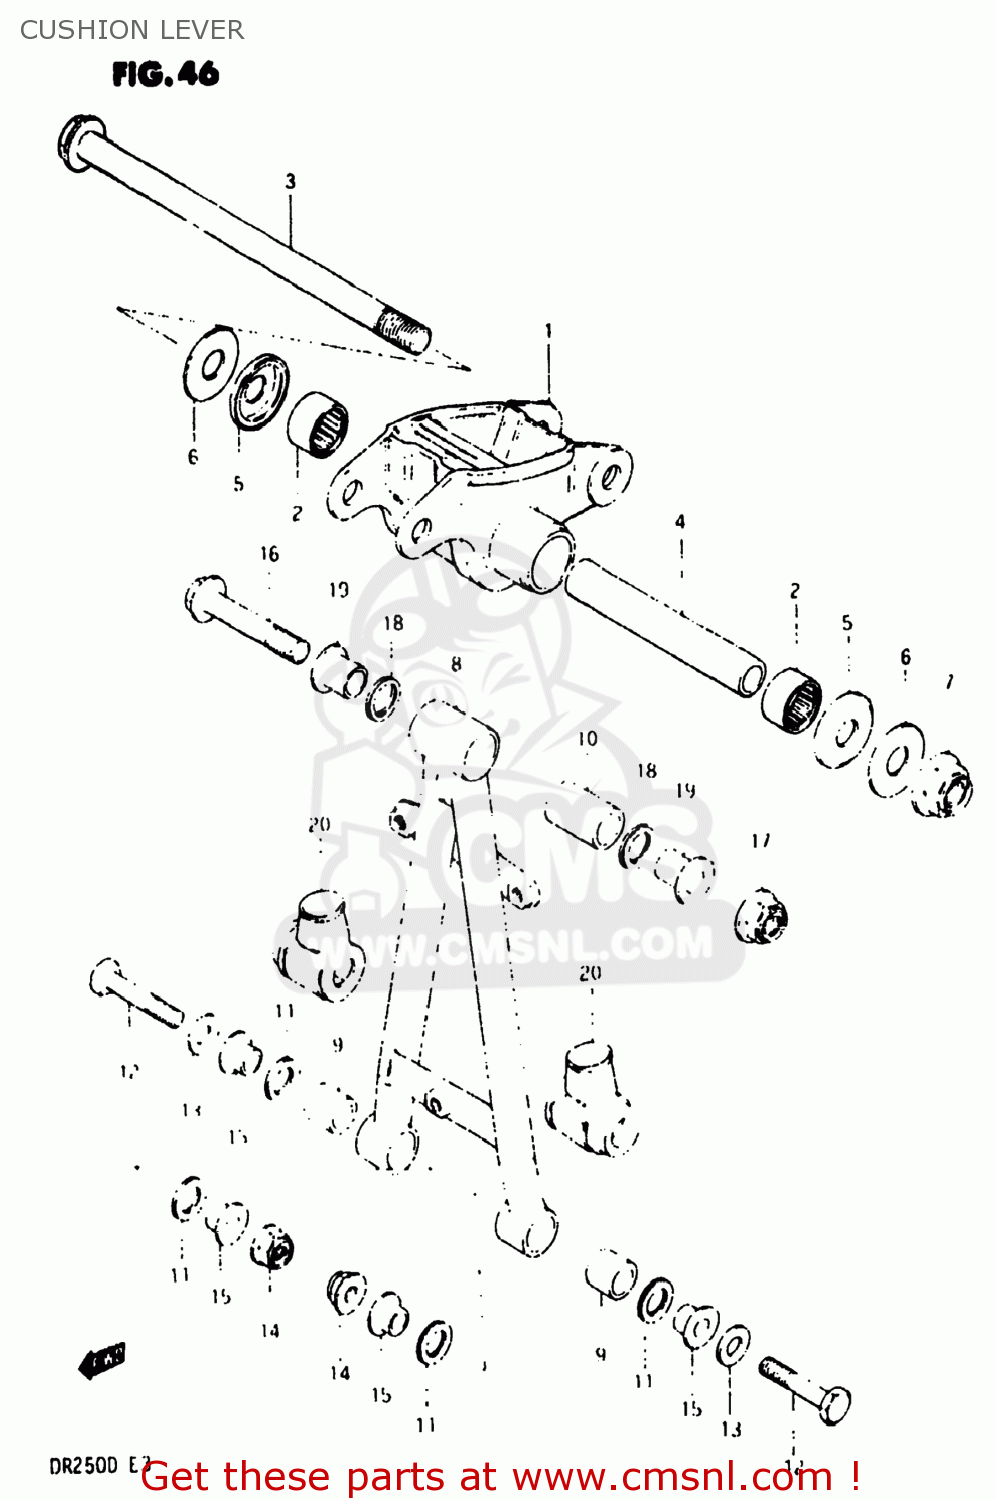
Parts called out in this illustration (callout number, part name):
1	LEVER SET,REAR CUSHION
2	BEARING(17X25X20)
3	SHAFT,REAR CUSHION LEVER
4	SPACER
5	DUST SEAL,RR CUSHION LEVER
6	WASHER
7	NUT 12MM
8	ROD SET,REAR CUSHION LEVER
9	BUSHING
10	BUSH,UPPER
11	DUST SEAL,RR CUSHION LOD LWR
12	BOLT,REAR CUSHION LEVER
13	WASHER
14	NUT
15	SPACER,RR CUSHION ROD LWR
16	BOLT(10X65)
17	NUT
18	DUST SEAL,LEVER CUSHION UNIT
19	SPACER,RR CUSHION ROD UPR
20	BOOT,REAR CUSHION ROD,LOWER
